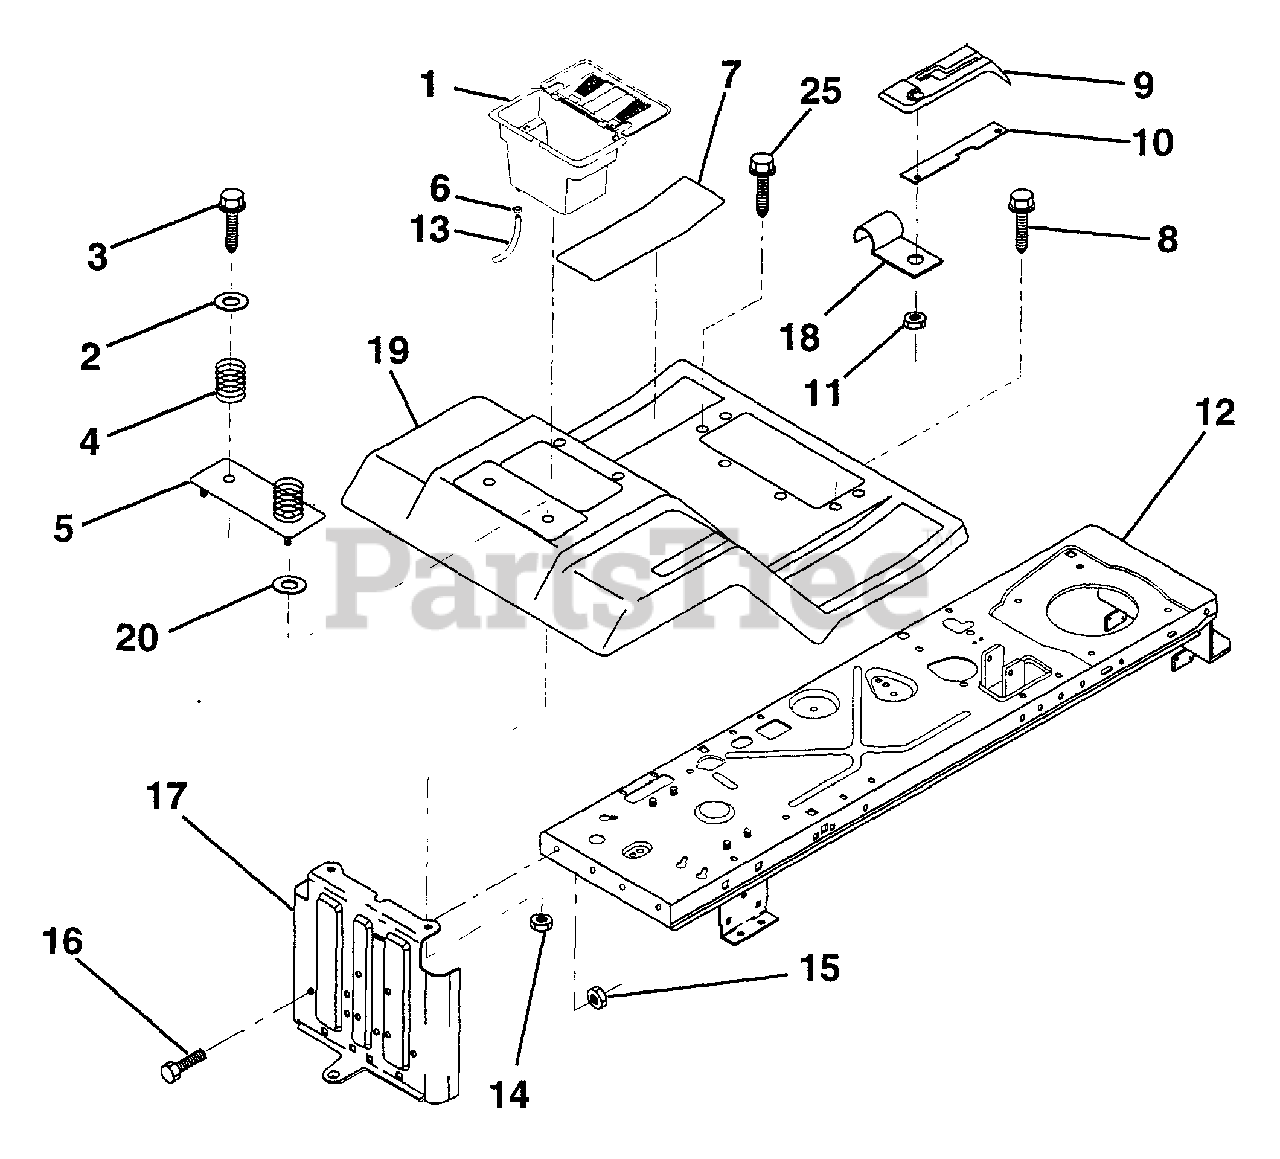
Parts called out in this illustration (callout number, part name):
1	Case, Battery
2	Washer 13/32 x 1-1/4 x 12 Ga.
3	Screw, Hex Wsh. Thrdrol. 3/8-16 x 3/4
4	Spring, Compression, Seat
5	Plate, Asm. Battery
6	Clamp, Hose
7	Pad, Footrest
8	Screw, Hex Wsh. Thrdrol. 5/16-18 x 3/4
9	Console, Shift Control
10	Bar, Shift Lock
11	Nut, Self-Thrd., Wsh. Head 3/16
12	Assembly, Frame
13	Tube, Battery Drain
14	Nut, Keps Hex 1/4-20 UNC
15	Nut, Crownlock 5/16-18
16	Bolt, Hex Hd. 5/16-18 UNC x 3/4
18	Clip, Insulated
19	Fender/Footrest
20	Washer 9/32 x 7/8 x 13 Ga.
25	Screw Hex Washer Thd. Roll 5/16-18 x 1
